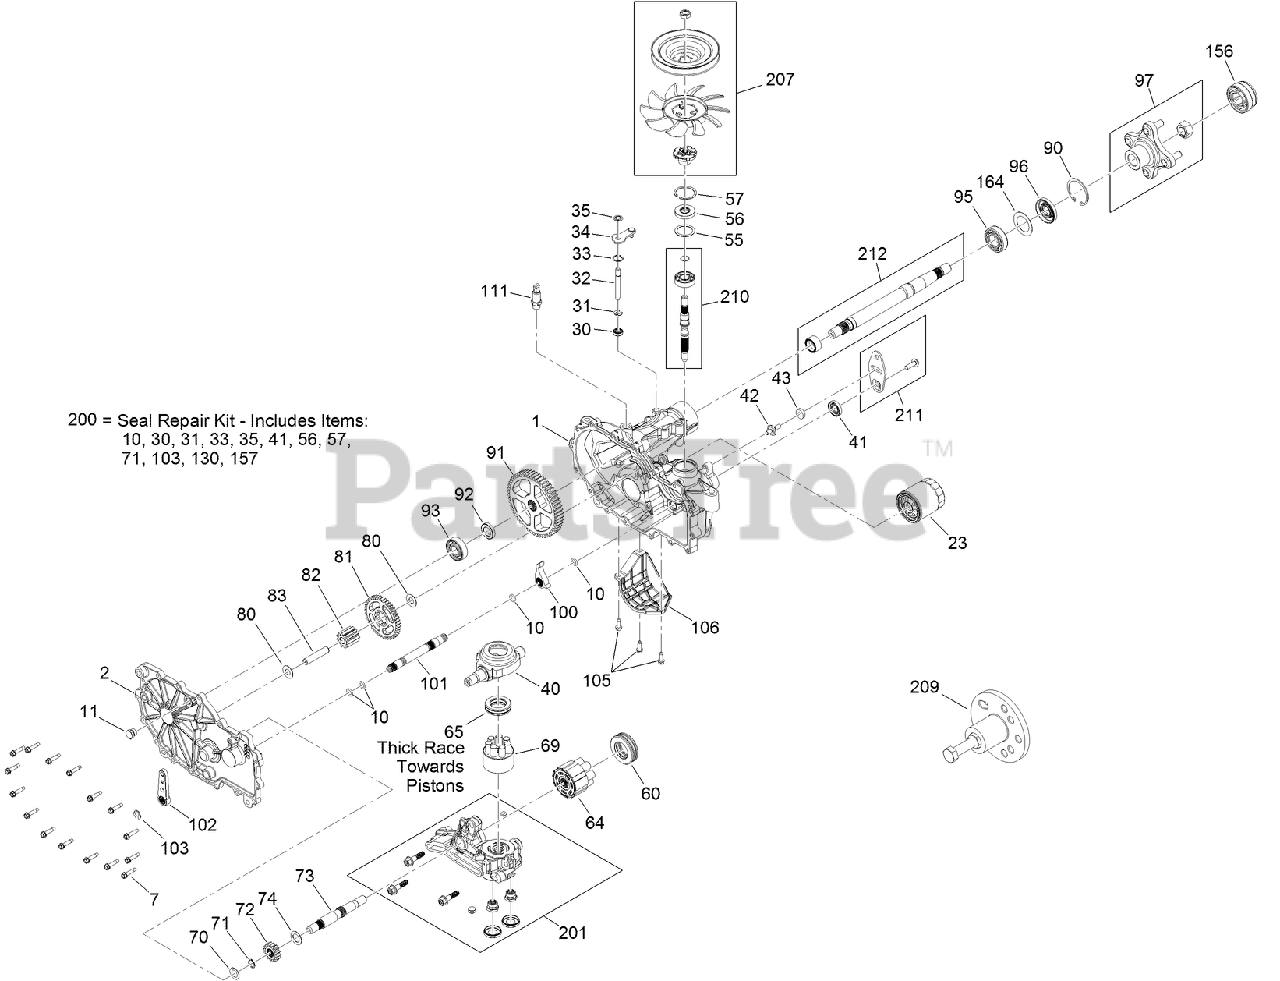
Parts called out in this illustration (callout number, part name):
1	MAIN HOUSING KIT
2	LH SIDE COVER KIT
7	SCREW-HHF
10	O-RING
23	ELEMENT-OIL FILTER, HYD
30	SEAL-LIP
31	RING-RETAINING, EXTERNAL
32	ROD-BYPASS
33	RING-RETAINING, INTERNAL
34	ARM-BYPASS
35	RING-RETAINING, EXTERNAL
40	SWASHPLATE-TRUNNION
41	SEAL-LIP
43	PUCK-FRICTION
55	SPACER
56	SEAL-LIP
57	RING-RETAINING
60	BEARING-THRUST
64	MOTOR CYLINDER BLOCK KIT
65	BEARING-THRUST
69	PUMP BLOCK ASM
70	WASHER-FLAT
71	RING-RETAINING
72	GEAR-16T
73	SHAFT-MOTOR
74	WASHER
80	WASHER
81	GEAR-43T
82	GEAR-11T
83	PIN-JACKSHAFT
90	RING-RETAINING
91	GEAR-54T
92	SPACER
93	BEARING KIT
95	INPUT BEARING KIT
96	SEAL-LIP
97	HUB KIT
100	PAWL-BRAKE
101	SHAFT-BRAKE, INBOARD
102	HANDLE-BRAKE
103	RING-RETAINING, EXT
106	GUARD-FILTER, LH
111	ADAPTER-STRAIGHT
156	COVER-NUT, AXLE
164	SPACER
200	SEAL KIT
201	CENTER SECTION KIT
207	FAN PULLEY KIT
210	INPUT SHAFT KIT
211	CONTROL ARM KIT
212	AXLE SHAFT KIT
